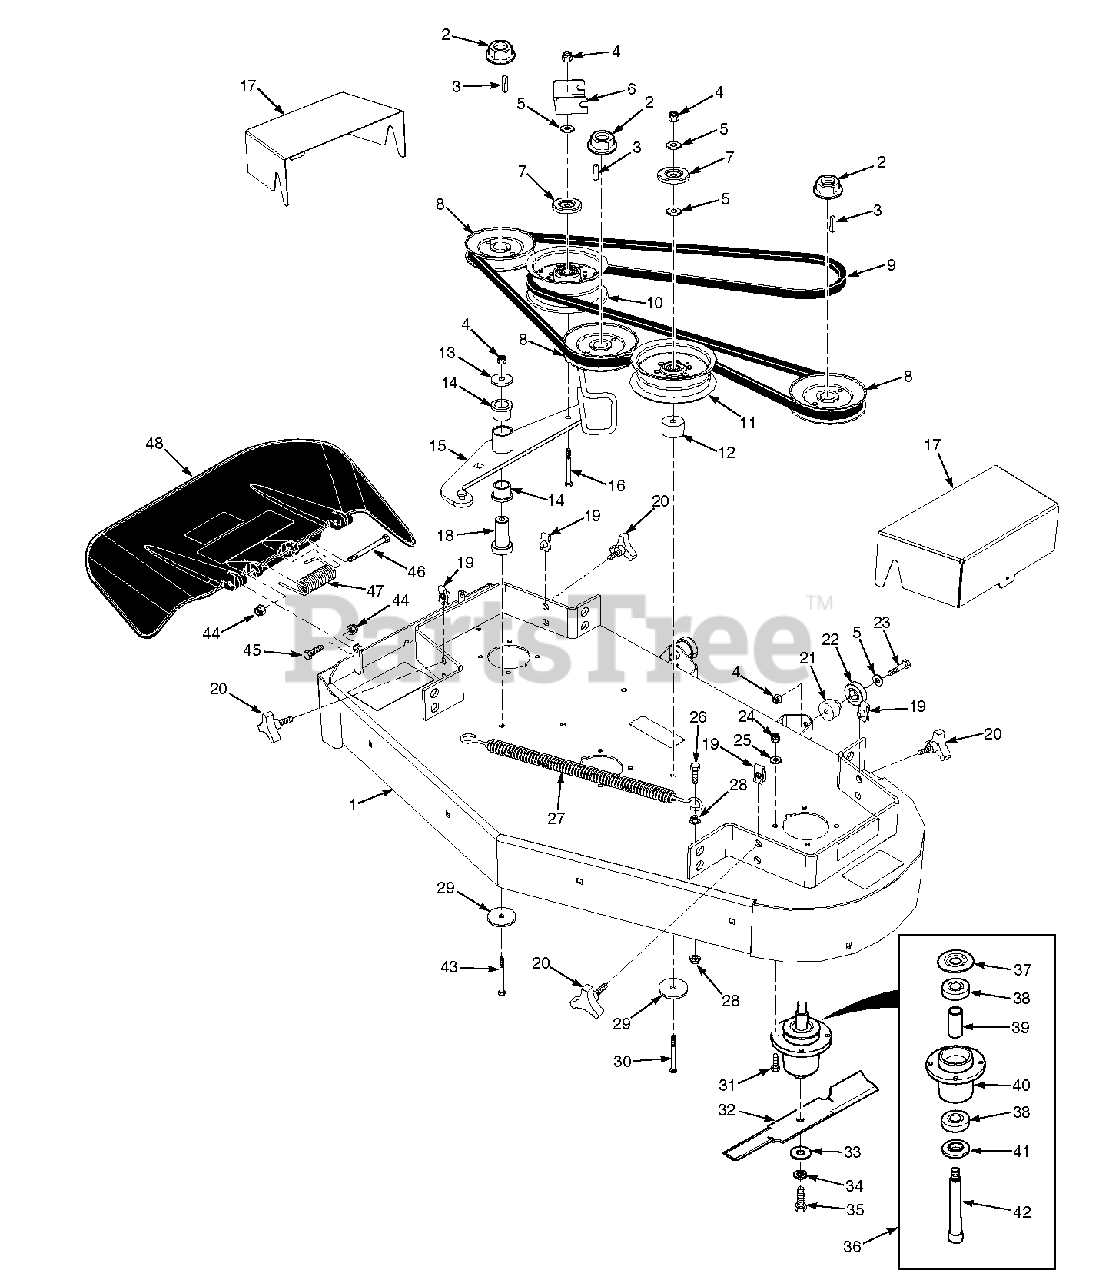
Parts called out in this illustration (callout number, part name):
1	Cutter Deck Weldment w/Decals
2	Nut, 3/4-16 Spiral Lock
3	Key, 1/4 x 1/4 x 1-1/4"
4	Nut, Elastic Stop 3/8-16
5	Flatwasher, 3/8-.391 x .938 x .105 HD
6	Bracket, Belt Guide
7	Dust Shield
8	Pulley, 5.13" Dia.
9	Belt, Cutter Deck
10	Pulley, 5" Idler
11	Pulley, 5" Idler
12	Spacer, Idler Pulley
13	Flatwasher, 3/8-.406 x 1-1/2"
14	Bearing
15	Idler Arm Assembly
16	Bolt, Hex Head 3/8-16 x 3-1/4"
17	Belt Cover, SFW 48
18	Pivot, Idler
19	U-Nut, 3/8-16
20	Knob, w/Stud
21	Spacer, Bearing
22	Bearing
23	Bolt, Hex Head 3/8-16 x 2-1/4"
24	Nut, Elastic Stop 5/16-18
25	Lockwasher, 5/16" Spring
26	Bolt, Hex Head 3/8-16 x 1-1/2" Gr.8
27	Spring, Deck Idler
28	Nut, Serrated Flange 3/8-16
29	Flatwasher, 3/8-.406 x 2-1/4 x .187
30	Bolt, Hex Head 3/8-16 x 3-1/2"
31	Bolt, Hex Head 5/16-18 x 1-1/2" Gr.8
32	Cutter Blade, 16-1/2"
33	Flatwasher, 5/8-.688 x 1-3/4 x .134 HD
34	Lockwasher, 1/2" Spring
35	Bolt, Hex Head 5/8-11 x 1-1/2"
36	Spindle Assembly
37	Debris Shield
38	Bearing
39	Spacer, Bearing
40	Spindle Housing Assembly
41	Protector, Bearing
42	Shaft, Spindle
43	Bolt, Hex Head 3/8-16 x 3-3/4"
44	Nut, Elastic Stop 5/16-18
45	Bolt, Hex Head 5/16-18 x 1-3/4"
46	Bolt, Hex Head 5/16-18 x 4-3/4"
47	Spring, Discharge Chute
48	Discharge Chute Assembly
